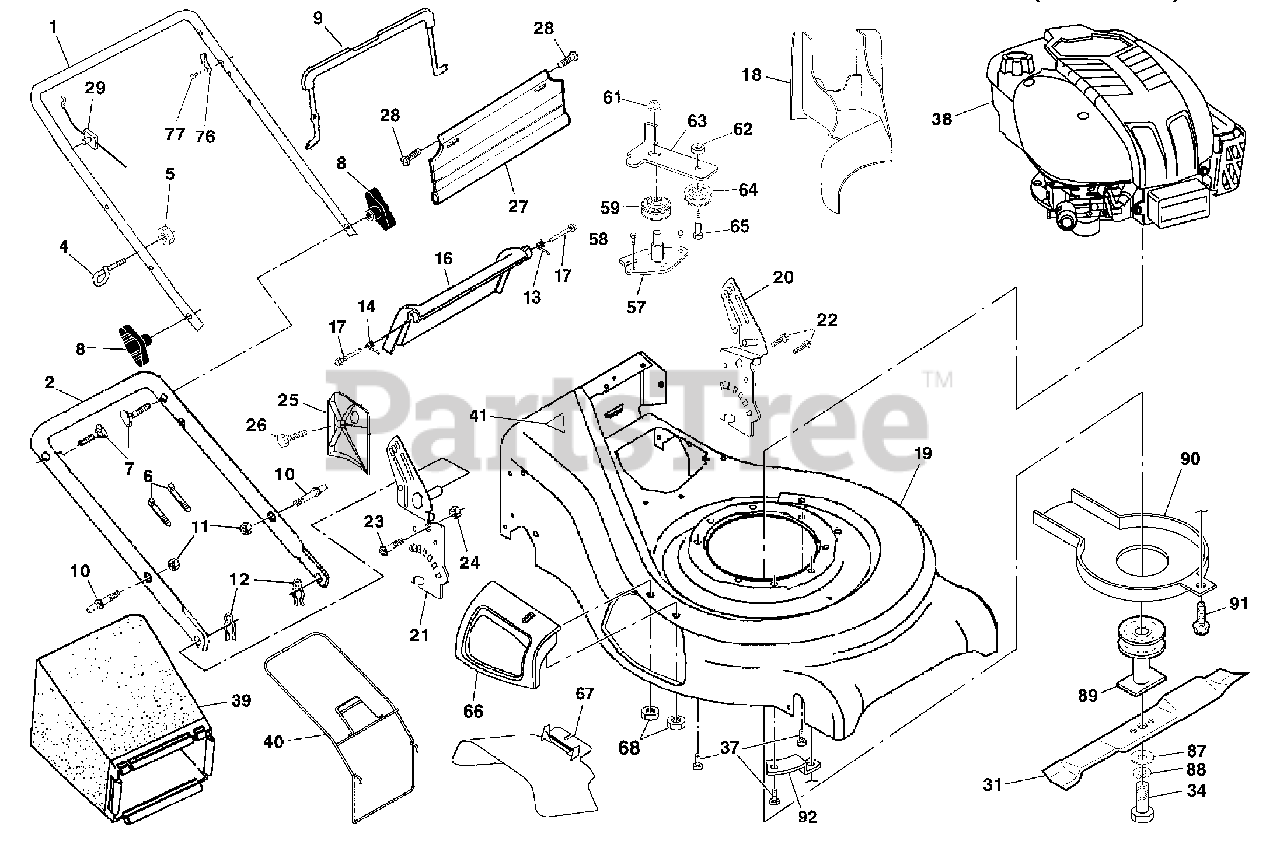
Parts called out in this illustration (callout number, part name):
1	Drive Control Assembly
2	Control Bar, Drive
3	Nut, Hex
4	Screw
5	Cover Drive
6	Screw, Threaded, Rolled #10-25 x .50
7	V-Belt
8	Nut, Flangelock, Zinc Plated 3/8-16
9	Pulley Assembly
10	Bearing, Ball
11	Screw
12	Seal, Output Shaft
13	Gear Case Assembly, Complete
16	Rod, Connecting
17	Spring, Extension
18	Spring, Selector
19	Knob, Selector Spring
20	E-Ring 7/8
21	Bearing, Support
22	Bearing, Ball
23	Retainer, Drive Assembly
24	Screw, Tapping, Hex Head 1/4-20 x .75
25	Bushing
26	Shaft, Output
28	E-Ring 7/16
29	Cover, Dust, Wheel
30	Gear, 24 Teeth
31	Nut, Flangelock
32	Wheel 9 x 2
33	Nut, Flangelock 3/8-16
34	Hubcap, Mag, Platinum
35	Shaft Assembly, Rear
36	Shaft Assembly, Front
37	Retainer, Front Shaft
38	Screw #12 x 5/8
39	Clip, Retainer
40	Wheel 8 x 2
41	Case, Lower
42	Case, Upper
44	Shaft, Input
45	Wire, Formed
46	Washer
47	Screw
48	Seal, Input Shaft
49	Pinion, Gear
50	Retainer, Drive, RH
51	Pawl
52	Spring, Torsion
53	Disc, Drive
54	Seal, Friction
55	Pinion Assembly, RH
56	Pinion Assembly, LH
57	Washer
58	Retainer, Drive, LH
